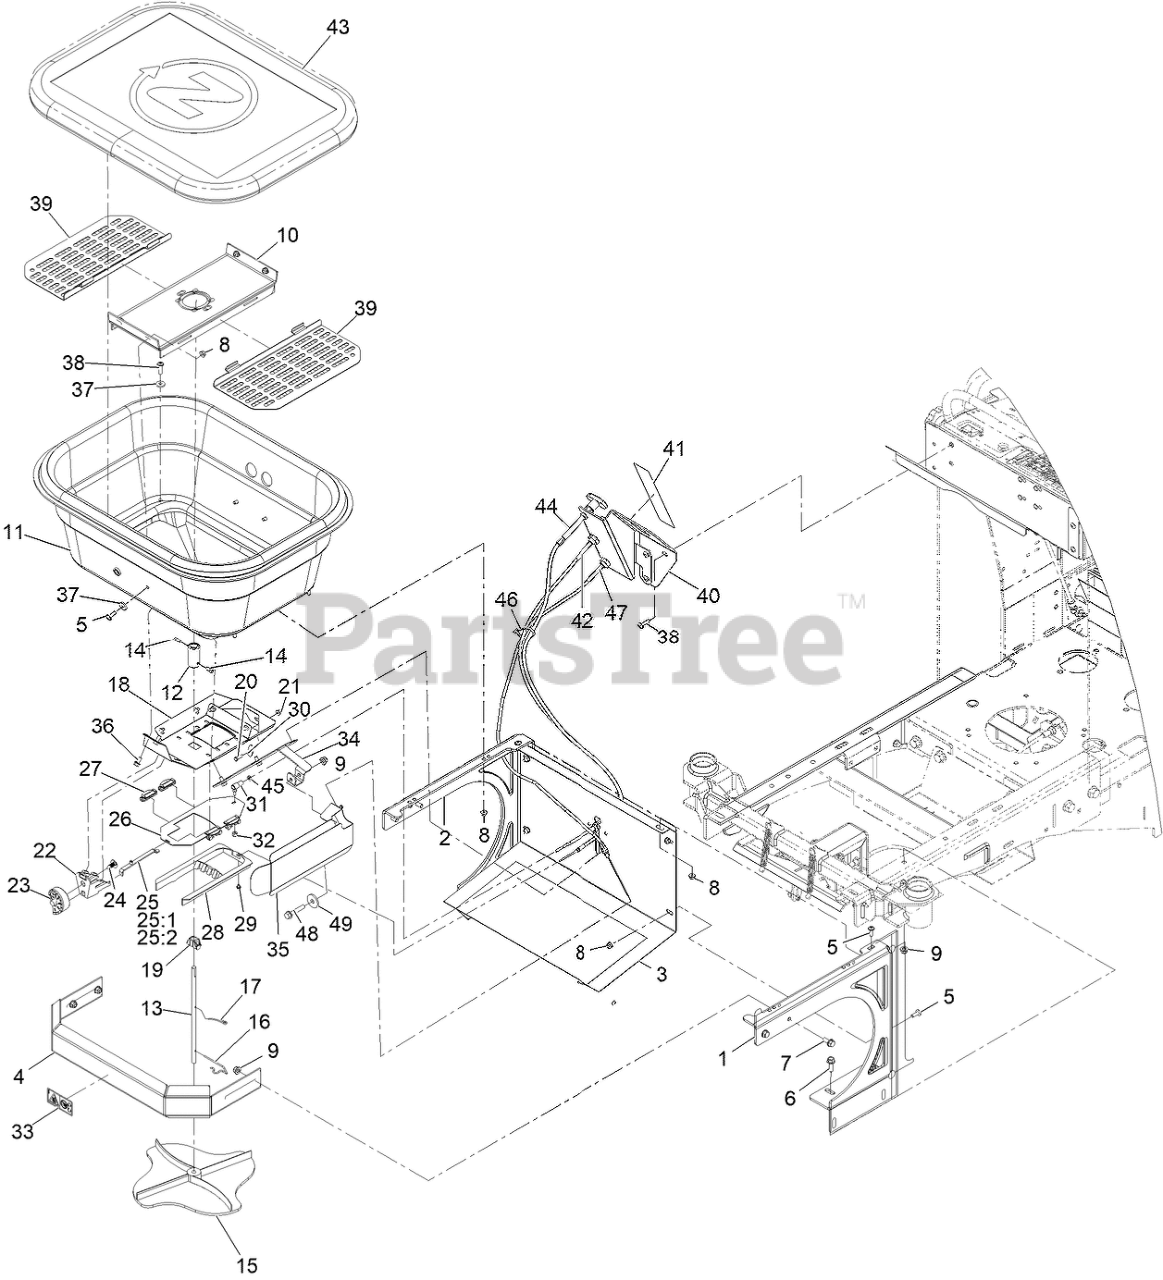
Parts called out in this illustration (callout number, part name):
1	WLD, FRAME, HOPPER, L, 120
2	WLD, FRAME, HOPPER, R, 120
3	BACKSHIELD, HOPPER, JR36
4	BUMPER, FRONT, HOPPER, 120
5	Screw-Hsbhf
6	SCREW-HHF
7	SCREW-HHF
8	Nut-Hex Flange
9	Nut-Hex Flange
10	PAN, HOPPER, 120
11	HOPPER-120LB
12	COUPLER-SS
13	SHAFT-HOPPER, 120
14	Screw-SQH
15	Spinner-Spreader
16	Clip-Spinner
17	WIRE-AGITATOR
18	BASE PLATE, HOPPER, 120
19	HOPPER BOTTOM BEARING
20	SCREW-HH
21	Nut-Hex Flange
22	MOUNT-DIAL
24	Footpad Fastener
25	RATE GATE LINK ASM
25:1	LINK-GATE, RATE
25:2	SCREW-SHOULDER, SLOTTED
26	Slide-Door, Hopper
27	GUIDE-RATE, GATE
28	DIFFUSER
29	WIRE-STOP
30	RETAINER, CABLE
31	BALL JOINT-SS
32	Nut,NYL Lock,#10-32,ST/ST 18-8
33	Decal-Dismemberment Hazard
34	MOUNT-DEFLECTOR, SIDE
35	Deflector-Side, Spreader
36	SCREW-HHF
38	Screw-Hsbhf
39	SCREEN, HOPPER, 120
40	Mount-Speedometer
41	Decal-Hopper Control
42	CABLE-PUSH/PULL
43	COVER-HOPPER, SMALL
44	120LB HOPPER CABLE
45	Nut,Hex Jam Mch Scr,10-32,Sst
46	TIE-CABLE
47	Cable-Control, Turn Lock 2.00 Trvl
48	Screw-HHF
49	WASHER
